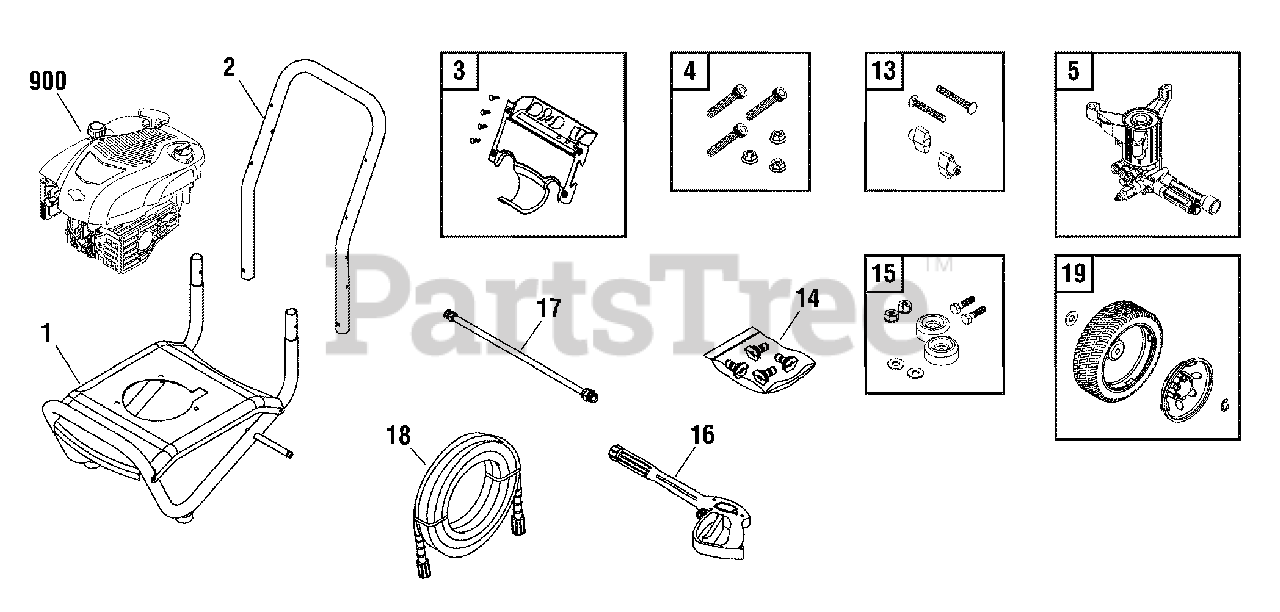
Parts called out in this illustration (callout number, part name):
2	HANDLE
4	KIT, Hardware, Pump Mounting
5	PUMP
13	KIT, Hardware, Handle
14	KIT, QC Nozzles
15	MOUNT, Vibration
16	GUN
17	EXTENSION, QC
18	HOSE
19	KIT, Wheel
900	* ENGINE
